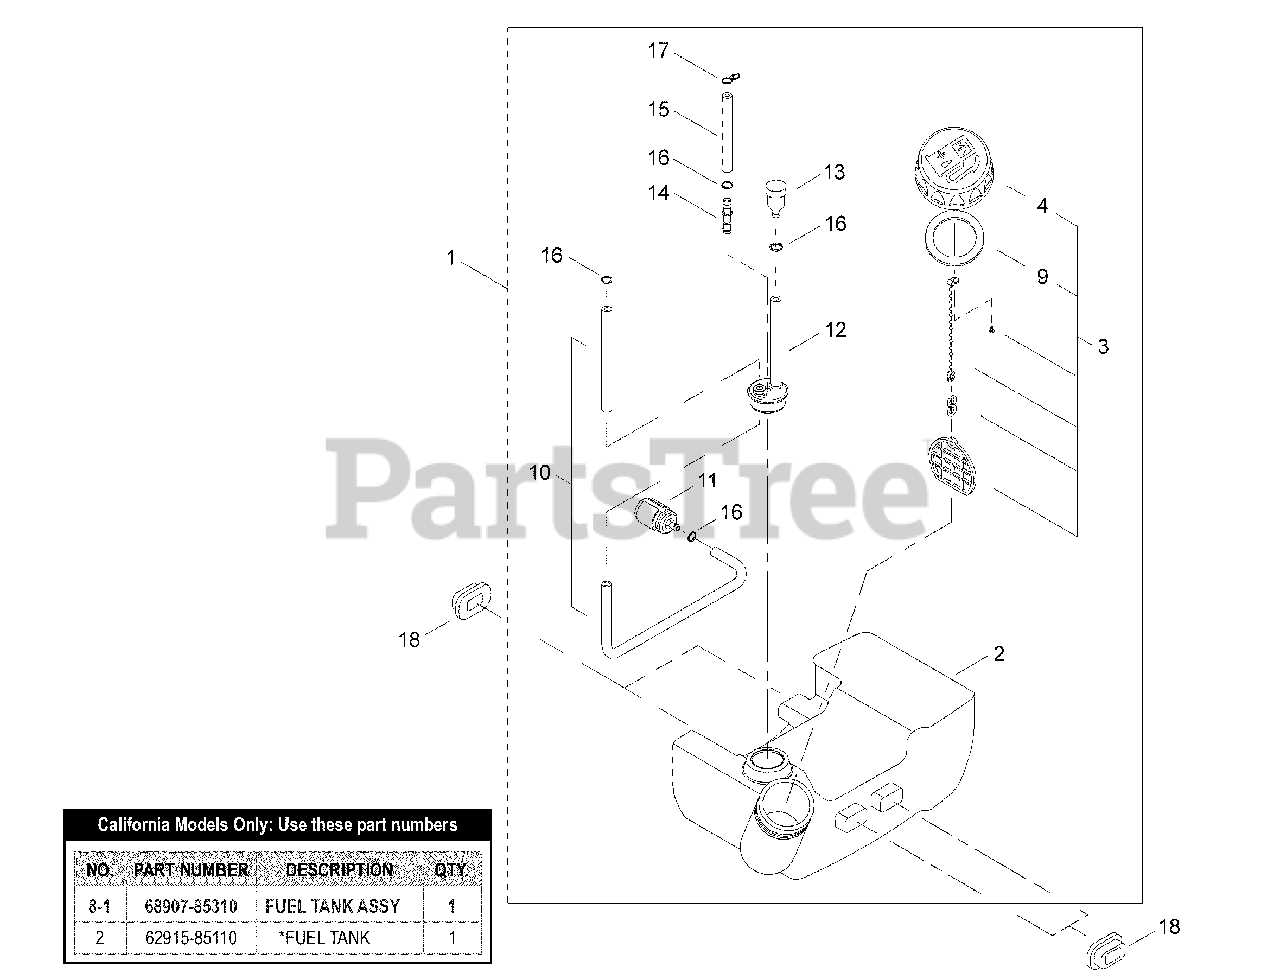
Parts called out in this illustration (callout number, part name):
1	FUEL TANK ASSY
2	TANK, FUEL
3	CAP ASSY
4	CAP, FUEL
9	GASKET, CAP
10	PIPE - FUEL
11	FILTER, FUEL
12	GROMMET
13	ELEMENT, BREATHER
14	CONNECTOR, PIPE
15	PIPE - 50 -- BLACK
16	RING, RETAINING - 6
17	CLIP - SPRING
18	CUSHION, FUEL TANK
